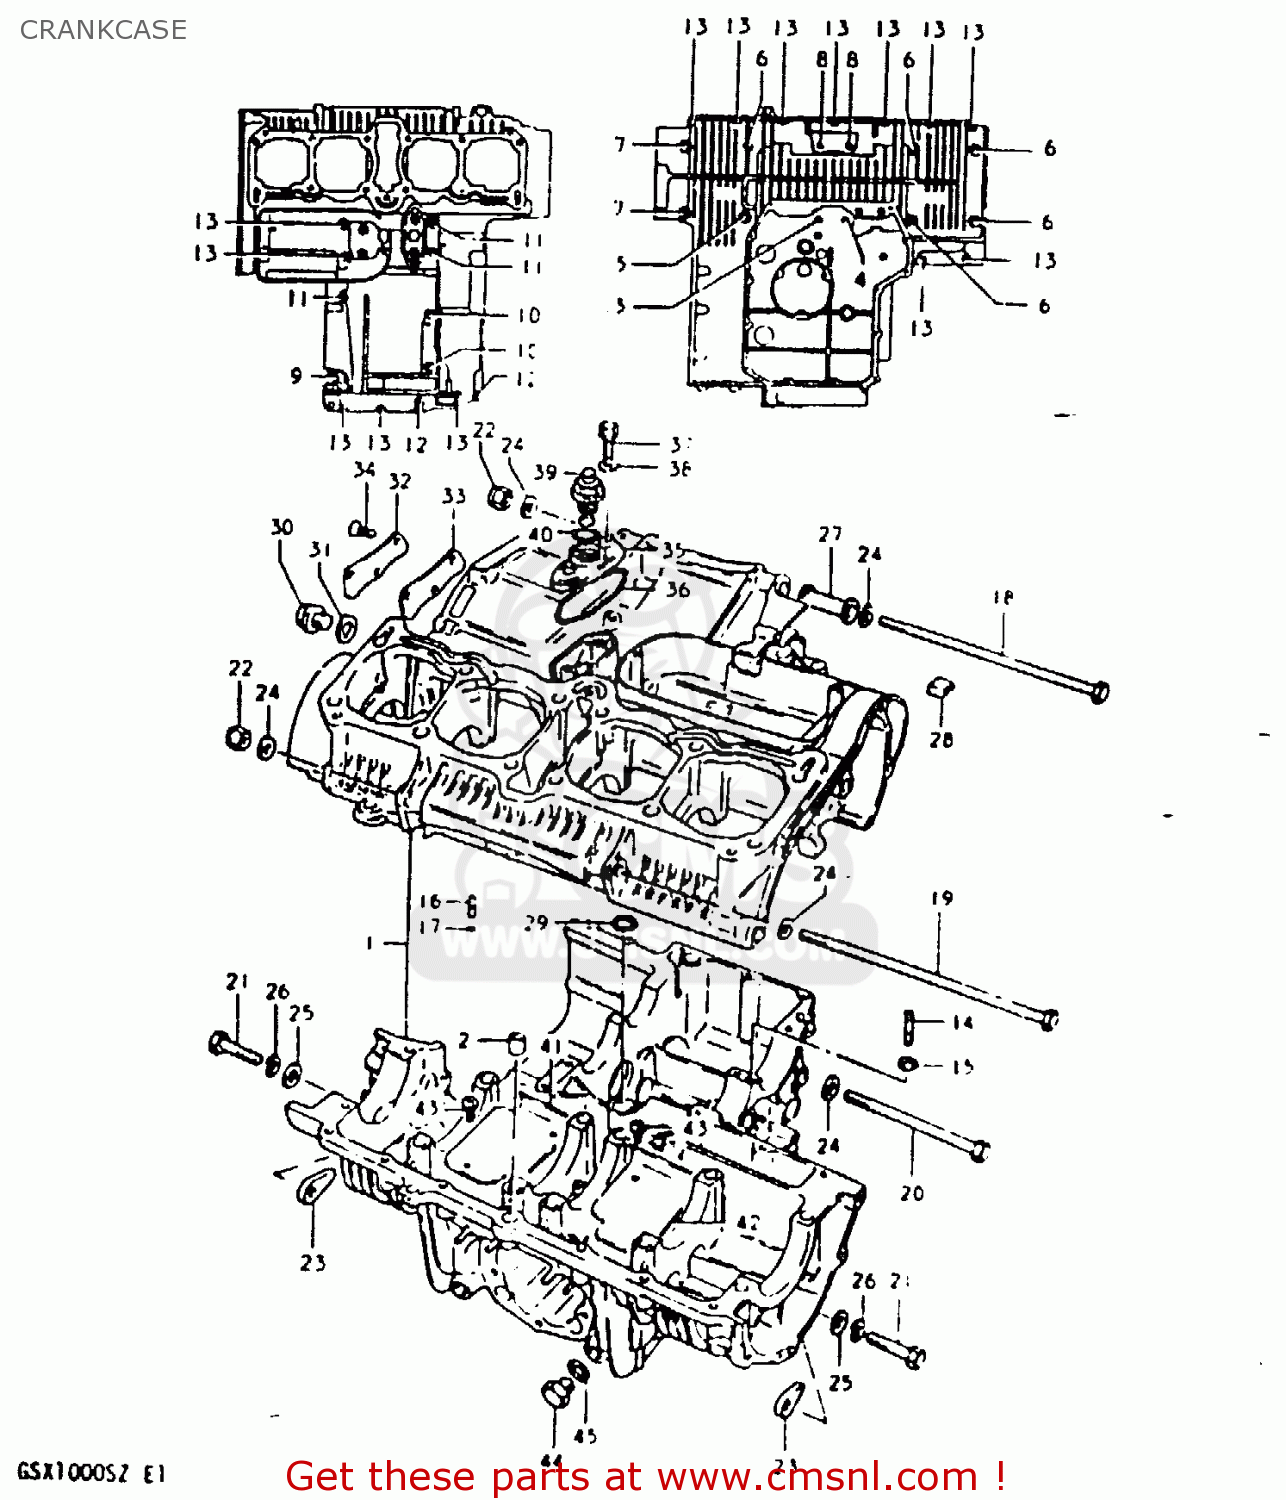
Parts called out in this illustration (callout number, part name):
1	CRANKCASE SET
2	PIN
3	BOLT 8X155
4	BOLT
5	BOLT
6	BOLT 8X90
7	BOLT 8X65
8	BOLT
9	BOLT
10	BOLT
11	BOLT (6X75)
12	BOLT
13	BOLT
14	STUD BOLT
15	NUT
16	UNION
17	O RING(D:1.05,ID:3.1)
18	BOLT(10X225)
19	BOLT(10X250)
20	BOLT(10X165)
21	BOLT 10X60
22	NUT
23	NUT
24	WASHER
25	WASHER(10.5X20X3.2)
26	LOCK WASHER
27	SPACER
28	PAD,CYLINDER
29	O RING(D:3.2,ID:12.9)
30	PLUG (14X12)
31	GASKET(14X19.2X2) (NAS)
32	CAP,OIL GALLERY
33	GASKET,OIL GALLERY (MCA)
34	SCREW
35	HOUSING,OIL PRESSURE SWITCH
36	O RING,PRESSURE SWITCH HOUSING
37	BOLT
38	GASKET (NAS)
39	SWITCH ASSEMBLY
40	O RING(D:1.9,ID:18.8)
41	PLATE,OIL SEPARATOR
42	PLATE,OIL SEPARATOR
43	SCREW
44	PLUG
45	GASKET(14X19.2X2) (NAS)
